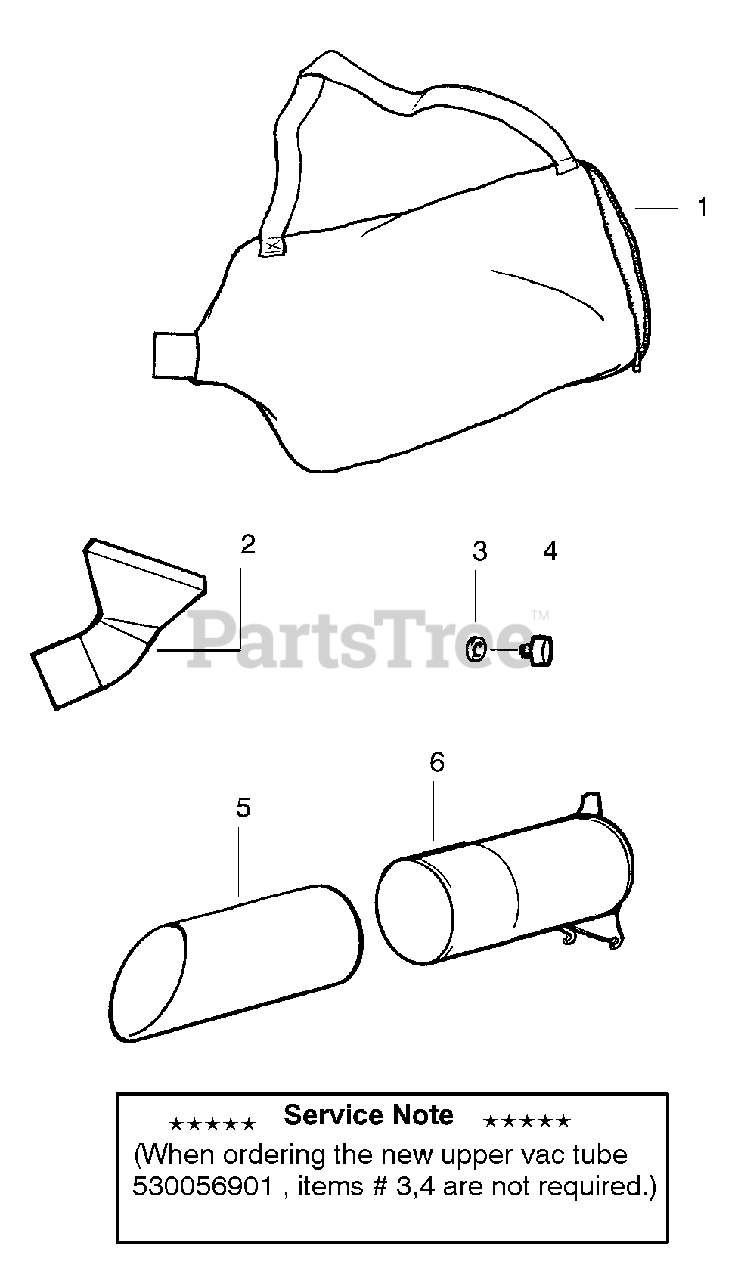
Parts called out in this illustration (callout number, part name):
1	Assy-Vac. Bag w/strap
2	Tube-Elbow Vac
3	Retainer-Vac Tube Knob
5	Tube-Lower Vac
6	Tube-Upper Vac
